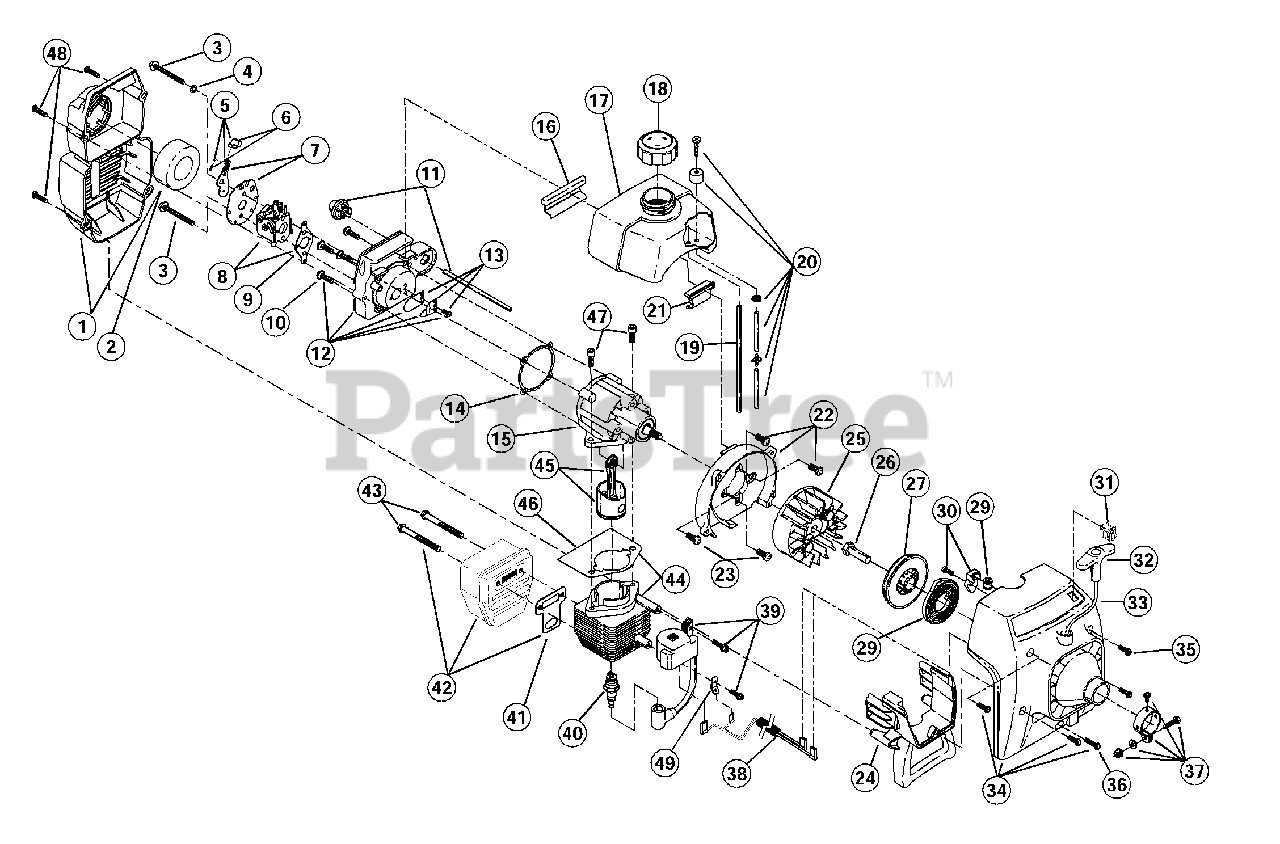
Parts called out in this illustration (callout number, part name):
1	Air Cleaner/Muffler Cover Assembly
2	Air Cleaner Filter
3	Carburetor Mounting Screw Assembly
4	Wavey Washer
5	Choke Lever Assembly
6	Choke Knob and Screw
7	Choke Assembly
8	Carburetor Assembly
9	Carburetor Gasket
10	Carb Mount Screw
11	Primer and Hose Assembly
12	Carb Mount Assembly
13	Reed Assembly
14	Carburetor Mount Gasket
15	Crank Case Service Assembly
16	Rear Mounting Pad
17	Fuel Tank Assembly
18	Fuel Cap Assembly
19	Fuel Return Line
20	Fuel Line Assembly
21	Front Mounting Pad
22	Shroud Assembly
23	Shroud Screw
24	Shroud Extension and Stand
25	Flywheel Assembly
26	Square Nut Drive
27	Recoil Pulley Assembly
28	Recoil Spring
29	Rope Guide
30	Pulley Retainer Assembly
31	Switch Assembly
32	Pull Handle
34	Starter Housing Assembly
35	Housing Screw
36	Cover Screw
37	Upper Clamp Assembly
38	Wire Lead
39	Module Assembly
40	Spark Plug
41	Exhaust Gasket
42	Muffler Assembly
43	Muffler Mounting Bolt Assembly
44	Cylinder Assembly
45	Piston and Rod Assembly
46	Cylinder Gasket
47	Cylinder Bolt
48	Cover Screw
49	Ground Tab
